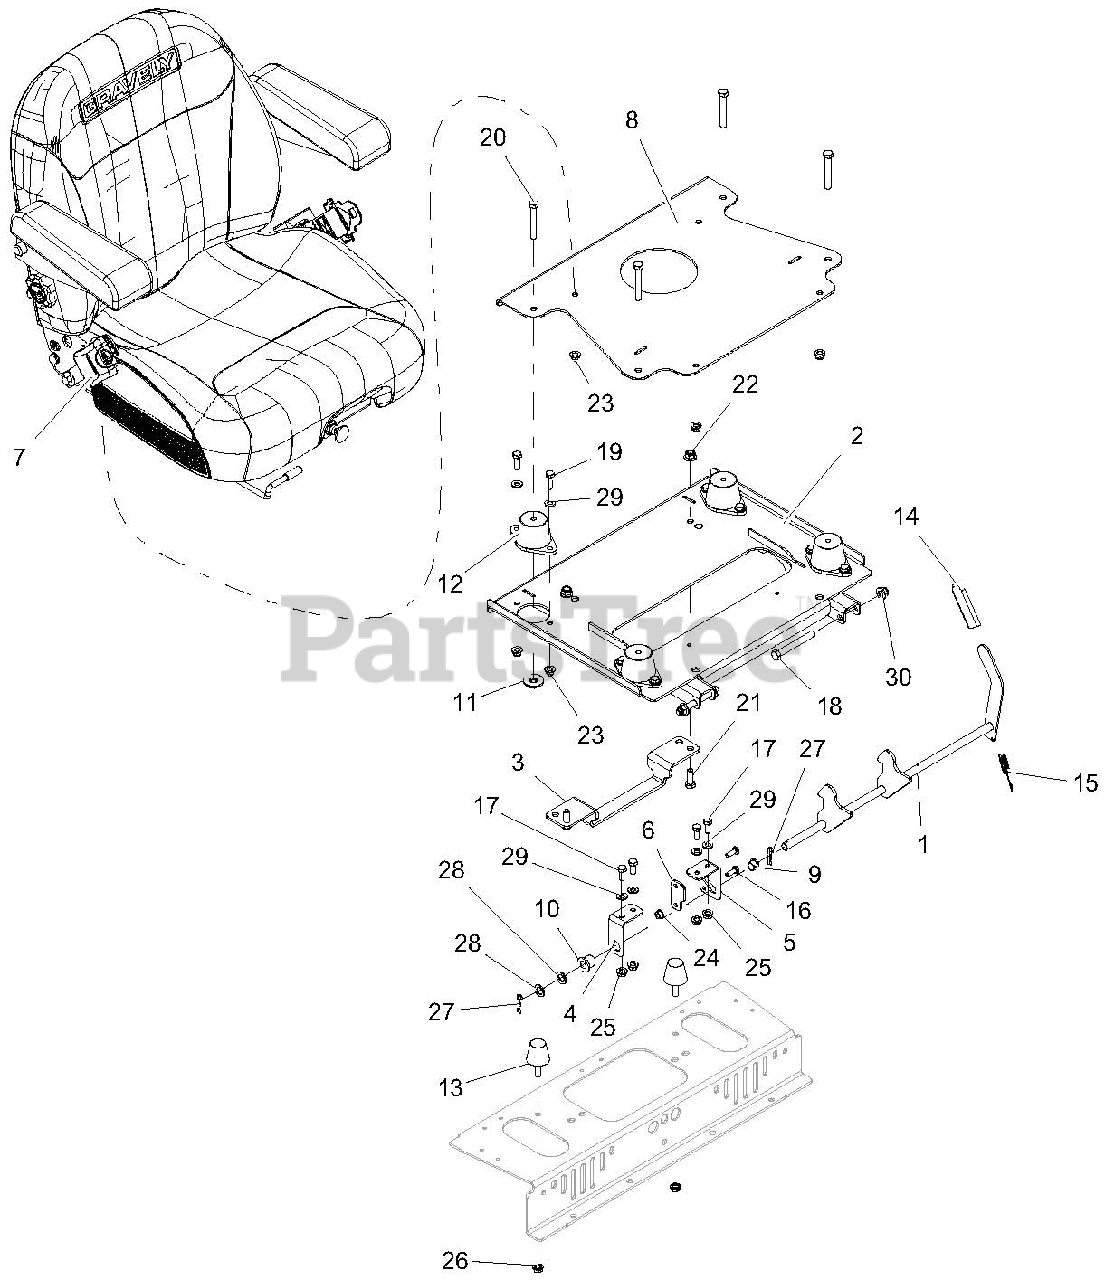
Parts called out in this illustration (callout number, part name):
1	WMT, SEAT LATCH
2	SEAT ISO MTG WMT W/SAFETY DECALS
3	BRKT, SEAT LATCH-BLACK
4	MOUNT, SEAT LATCHH- R
5	MOUNT, SEAT LATCHH- L
6	RETAINER-SEAT LATCH
7	SEAT, AIR SUSPENSION
8	WLDMT, SEAT MOUNTING
9	BUSHING, POLYLINER - .50 SPLIT
10	BSHG, FLANGE .515 X .750 X .745 X 1.00 NYLON
11	WLDMT, SEAT RETAINER
12	MOUNT, ISOLATOR
13	BUMPER, STUD MOUNTED CONE SHAPED
14	GRIP-VINYL-YELLOW .125 x 1.0 x 3.
15	SPRG, EXTENSION
16	BLT-HEX .25-20X.75 GR5 YWZC
17	BLT-HEX .31-18X.75 GR5 YWZC
18	BLT-HEX .38-16X3.25 GR5 YWZC
19	BLT-HEX .31-18X1.00 GR5 YWZC
20	BLT-HEX .38-16X2.50 FTH GR5 YWZC
21	BLT-HEX .38-16X1.00 GR5 YWZC
22	NUT-LK-NYL-FLG .38-16 YWZC
23	NUT-LK-NYL-FLG .31-18 YWZC
24	NUT, LK-TOP-FLG .25-20 YWZC
25	NUT, LK-TOP-FLG .312-18 YWZC
26	@NUT-SPNLK-FLG .312-18 YWZC
27	PIN-HAIR INT .08X.38X1.42 YWZC
28	WSHR-FL-STL .520X.827X.062 YWZC
29	WSHR-FL-STL.344X.688X.065YWZC
30	NUT-LK-NYL-FLG .38-16 YWZC
